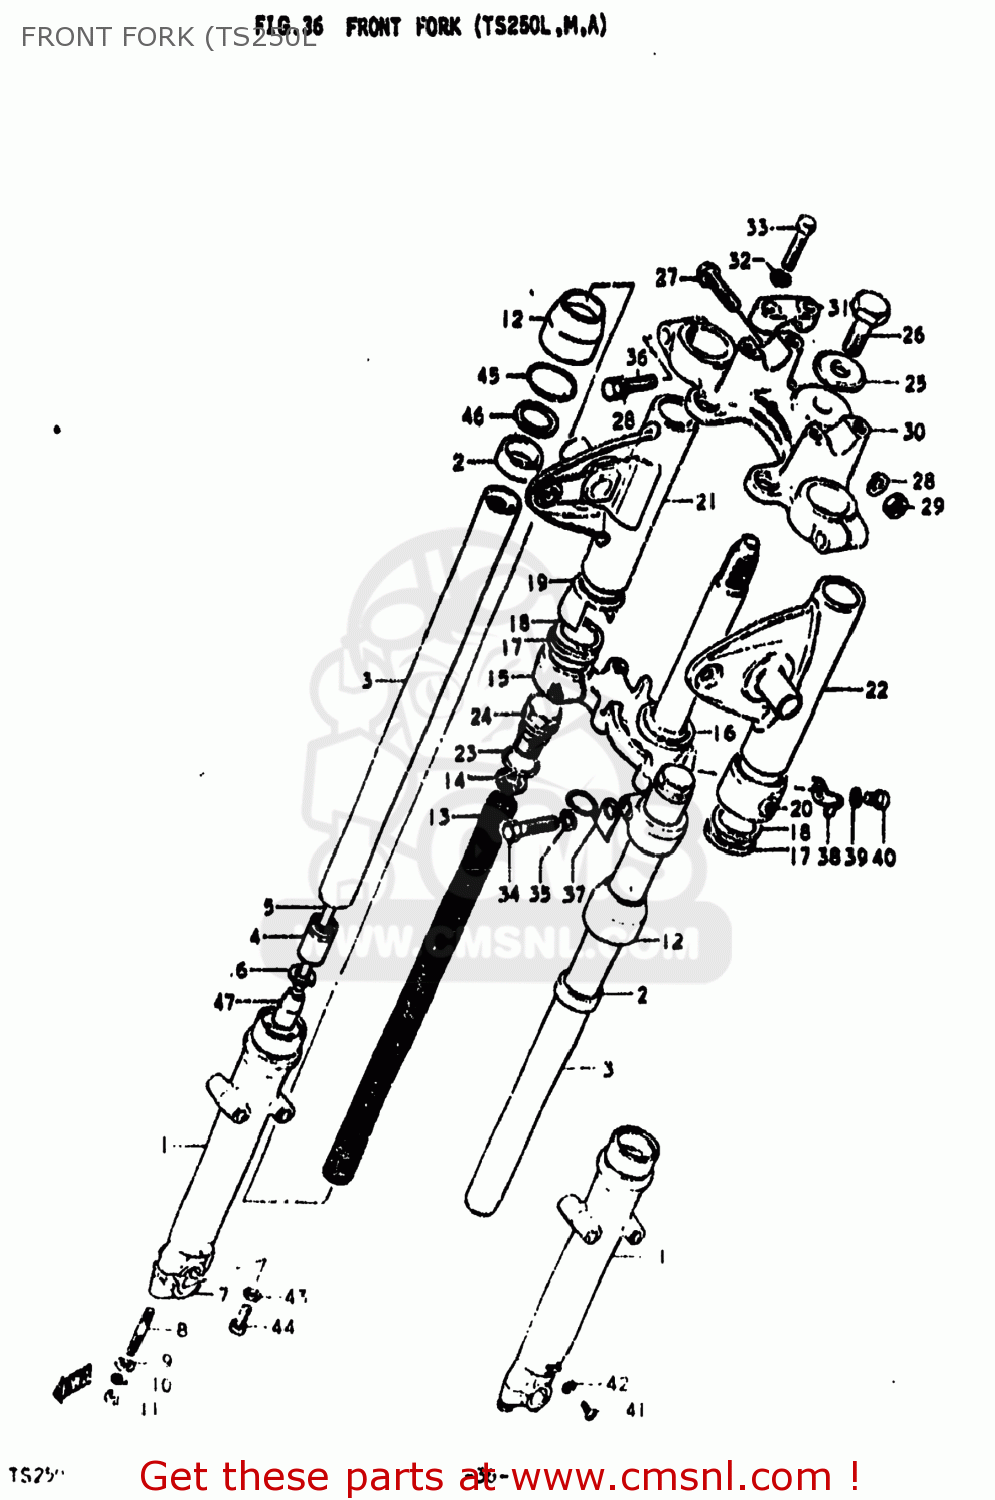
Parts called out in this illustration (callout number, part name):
0	DAMPER SET
1	TUBE,OUTER,RIGHT
2	SEAL,OIL
3	TUBE,FORK,INNER
4	PISTON L
5	CYLINDER,FRONT FORK
6	SNAP RING
7	HOLDER,AXLE
8	BOLT,STUD
9	WASHER
10	LOCK WASHER
11	NUT (8MM)
12	DUST SEAL,FRONT FORK
13	SPRING,FRONT FORK
14	SEAT,FRONT FORK SPRING
15	STEM,STEERING
16	RACE,STEERING OUTER LWR
17	GUIDE, COVER
18	CUSHION,HEADLAMP BRACKET
19	CUSHION,HEADLAMP BRACKET
21	BRACKET,HEADLAMP HOUSING
22	BRACKET,HEADLAMP,LEFT
23	O RING
24	CAP,FORK INNER TUBE
25	WASHER
26	BOLT,FORK INNER TUBE
27	BOLT,FORK INNER TUBE F
28	LOCK WASHER
29	NUT
30	HEAD,STEERING STEM
31	HOLDER,HANDLEBAR
32	LOCK WASHER
33	Bolt
34	BOLT,FR FORK LWR(12X33)
35	WASHER,LOCK 12
36	BOLT,FORK INNER TUBE F
37	CLIP
38	CLIP
39	LOCK WASHER
40	SCREW
41	SCREW
42	GASKET,DRAIN,PLUG (NAS)
43	GASKET (NAS)
44	BOLT,FORK CYLINDER(10X25)
45	RING,OIL SEAL STOPPER
46	WASHER, OIL SEAL
47	PIECE,OIL LOCK
